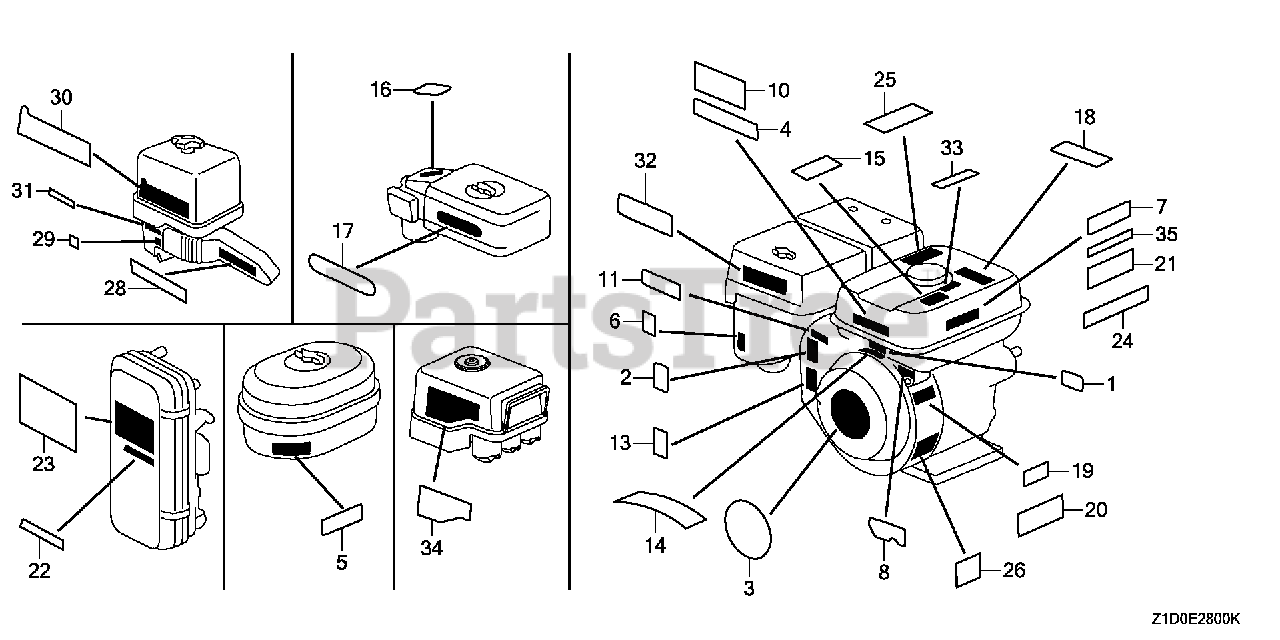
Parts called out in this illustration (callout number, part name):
3	EMBLEM (GX270)
6	MARK, CHOKE
13	LABEL, WARNING (NOT CERTIFIED FOR SALE)
21	MARK, OPERATOR CAUTION (ENGLISH)(MADE IN THAI)
25	MARK, EX. CAUTION (ENGLISH)
32	MARK, SALES POINT
